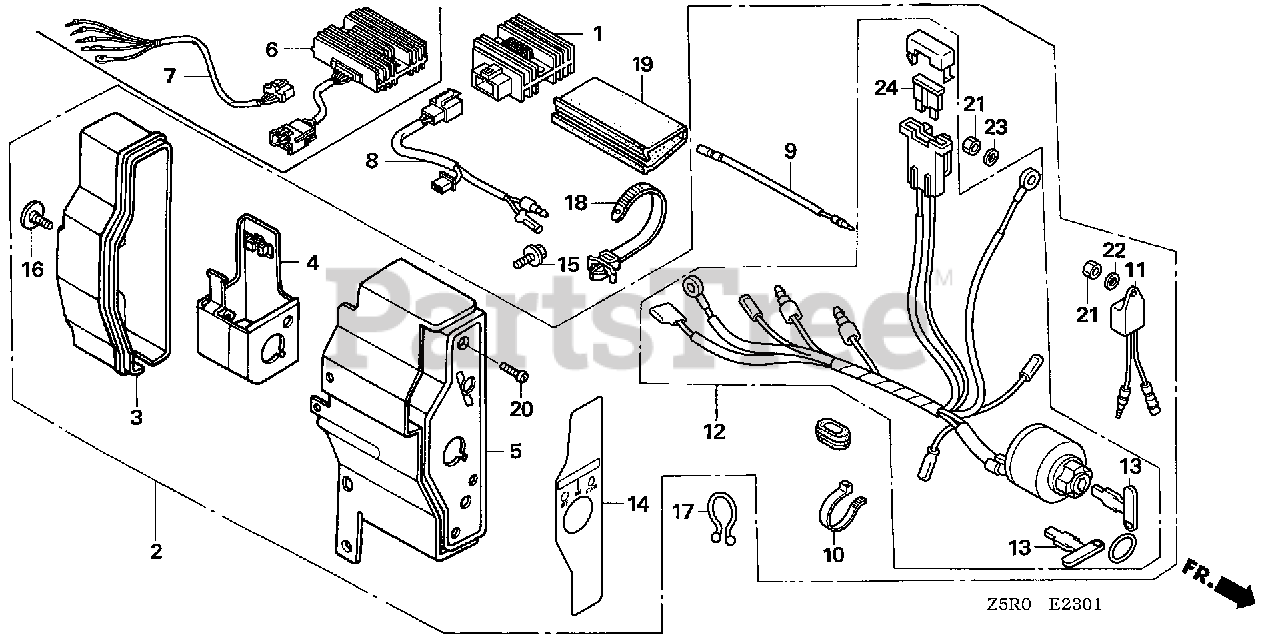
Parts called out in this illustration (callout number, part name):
2	BOX ASSY., CONTROL (10A) *NH1* (BLACK)
2	BOX ASSY., CONTROL (10A) *R280* (POWER RED)
3	CASE, CONTROL
4	BRACKET, CASE MOUNTING
5	PANEL, CONTROL *NH1* (BLACK)
5	PANEL, CONTROL *R280* (POWER RED)
10	BAND
12	SWITCH ASSY., COMBINATION (10A)
13	KEY
14	MARK, CONTROL BOX (EXP)
15	BOLT, FLANGE (6X12) (CT200)
16	SCREW, SPECIAL (6X12)
17	CLIP, PURSE LOCK
18	STRAP, CABLE (118MM) *NH1L* (Honda Code 1170653). (BLACK)
19	TUBE, FASTENER (30)
20	SCREW, PAN (4X12)
21	NUT, HEX. (4MM)
23	WASHER, SPRING (4MM)
24	FUSE, BLADE (15A)
